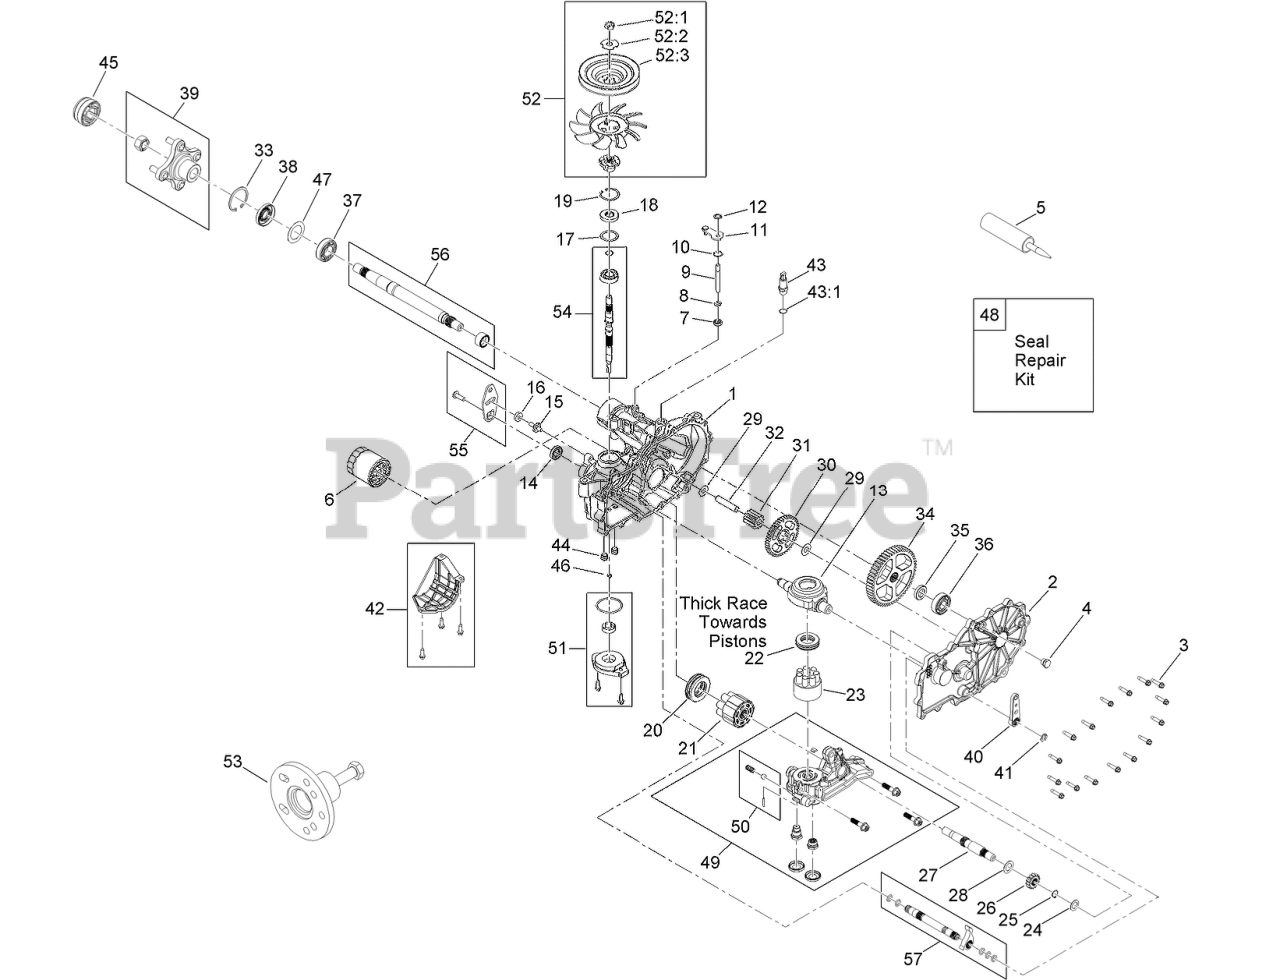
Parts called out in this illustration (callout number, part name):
1	MAIN HOUSING KIT
2	RH SIDE COVER KIT
3	SCREW-HHF
5	SEALANT
6	ELEMENT-OIL FILTER, HYD
7	SEAL-LIP
8	RING-RETAINING, EXTERNAL
9	ROD-BYPASS
10	RING-RETAINING, INTERNAL
12	RING-RETAINING, EXTERNAL
13	SWASHPLATE-TRUNNION
14	SEAL-LIP
16	PUCK-FRICTION
17	SPACER
18	SEAL-LIP
19	RING-RETAINING
20	BEARING-THRUST
21	CYLINDER BLOCK ASM KIT
22	BEARING-THRUST
23	PUMP BLOCK ASM
24	WASHER-FLAT
25	RING-RETAINING
26	GEAR-14T
27	SHAFT-MOTOR
28	WASHER
29	WASHER
30	GEAR-45T
31	GEAR-11T
32	PIN-JACKSHAFT
33	RING-RETAINING
34	GEAR-54T
35	SPACER
36	BEARING KIT
37	BEARING-BALL
39	HUB KIT
40	HANDLE-BRAKE
41	RING-RETAINING, EXT
42	FILTER GUARD KIT
43	ADAPTER-STRAIGHT
43:1	O-RING
44	TUBE-CHARGE
45	COVER-NUT, AXLE
46	SEAL-GEROTOR
47	SPACER
48	SEAL KIT
49	RH CHARGE CENTER SECTION KIT
50	CHARGE RELIEF KIT
51	CHARGE KIT
52	FAN AND PULLEY KIT
52:1	NUT-HJ
52:2	WASHER-SLOTTED
52:3	PULLEY-5.34
54	INPUT SHAFT KIT
55	CONTROL ARM KIT
56	AXLE SHAFT KIT
57	BRAKE SHAFT KIT
